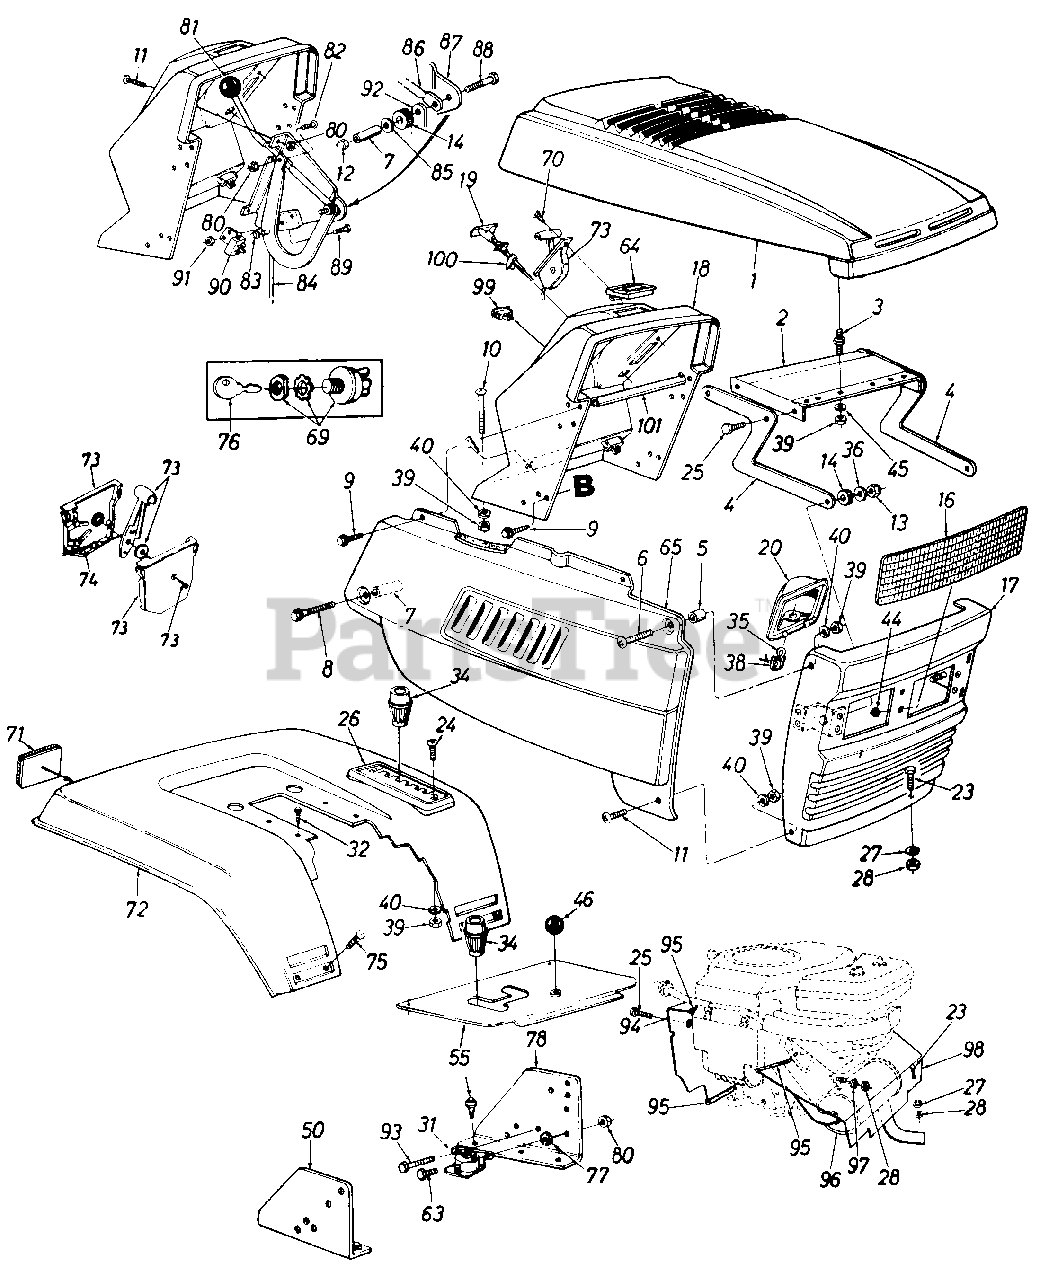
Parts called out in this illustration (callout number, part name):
2	Hood Plate
3	Double Ended Stud 1/4-20 Thd.
4	Hood Hinge
5	Spacer .34" I.D. x .437"
6	Truss Hd. Mach. Scr. 1/4-20 Thd.
7	Spacer .26" I.D. x .375"
8	Hex Wash. TT-Tap Scr. 1/4-20 x 1.75" Lg.
9	Hex T-Tap Scr. 1/4-20 x .75" Lg.
10	Truss Mach. Scr. 1/4-20 x 1.75" Lg.
11	Truss Mach. Scr. 1/4-20 x .5" Lg.
12	Hex Ins. L-Nut 1/4-20 Thd.
13	Hex L-Nut 5/16-18 Thd.
14	Rubber Washer
16	Headlight Lens
19	Choke Control
20	Headlight Housing
23	Hex Bolt 5/16-18 x .75" Lg.
24	Truss Mach. Scr. 1/4-20 x .75" Lg.
25	Hex Wash. Hd. Scr. 1/4" x .5" Lg.
26	7-Speed Index Brkt.
27	L-Wash. 5/16" I.D.
28	Hex Nut 5/16-18 Thd.
31	Solenoid
32	Hex Hd. Rolling Scr. 5/16-24 x .75" Lg.
34	Shift Knob
35	Lamp
36	Bell-Wash. 34" I.D. x 37"
38	Socket
39	Hex Nut 1/4-20 Thd.
40	L-Wash. 1/4" I.D.
44	Speed Nut 5/16" I.D.
45	Bell-Wash. .265" I.D. x .75" O.D.
46	Ball Knob Brake
50	Dash Support Brkt.-R.H.
55	Transmission Cover Ass'y.
63	Hex Bolt 1/4-20 x .5" Lg.
64	Ammeter
70	Truss Mach. AB-Tap Scr. #10 x .5" Lg.
71	Reflector
74	Throttle Control Wire 35" Lg.
75	Carriage Bolt 1/4-20 x .5" Lg.
76	Key
77	Ext. L-Wash. 1/4" I.D.
78	Dash Support Brkt.-L.H.
80	Hex Sems Nut 1/4-20 Thd.
81	Ball Knob
82	Hex Bolt 1/4-20 x .62" Lg.
83	Push Nut
84	PTO Rod
85	Fl-Wash. .281" I.D. x .73"
86	PTO Lever
87	Deck Clutch Control Brkt.
88	Hex Bolt 1/4-20 x 2.5" Lg.
89	Truss Mach. Scr. #10-24 x .5" Lg.
90	Safety Switch
91	Hex Nut #10-24 Thd.
92	PTO Bracket
93	Self Clinching Stud 1/4-20 x .5" Lg.
94	Engine Baffle
95	Trim Strip 10" Lg.
96	Muffler
97	Spec. L-Wash. 5/16" I.D.
98	Front Heat Shield
99	Light Switch
100	Retainer Clip
101	Dash Support Tube
17459-0638	PANEL-SIDE-LH - MTD/TROY-BILT RED (0638)
